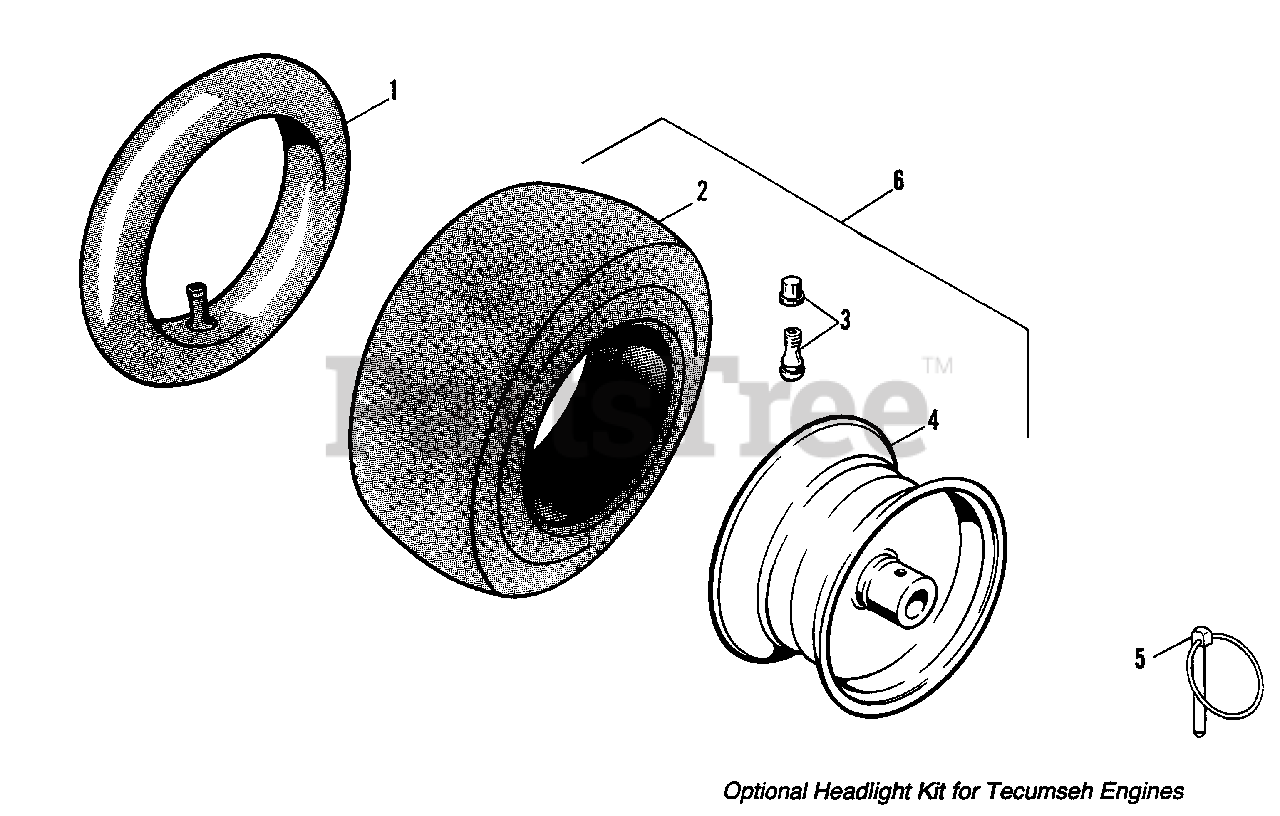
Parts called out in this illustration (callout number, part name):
2	TIRE, (Snow Hog)
3	VALVE STEM & CAP
4	WHEEL ASSY.
6	WHEEL & TIRE ASSY. (Incl. Ref. Nos. 1, 3 & 4)
